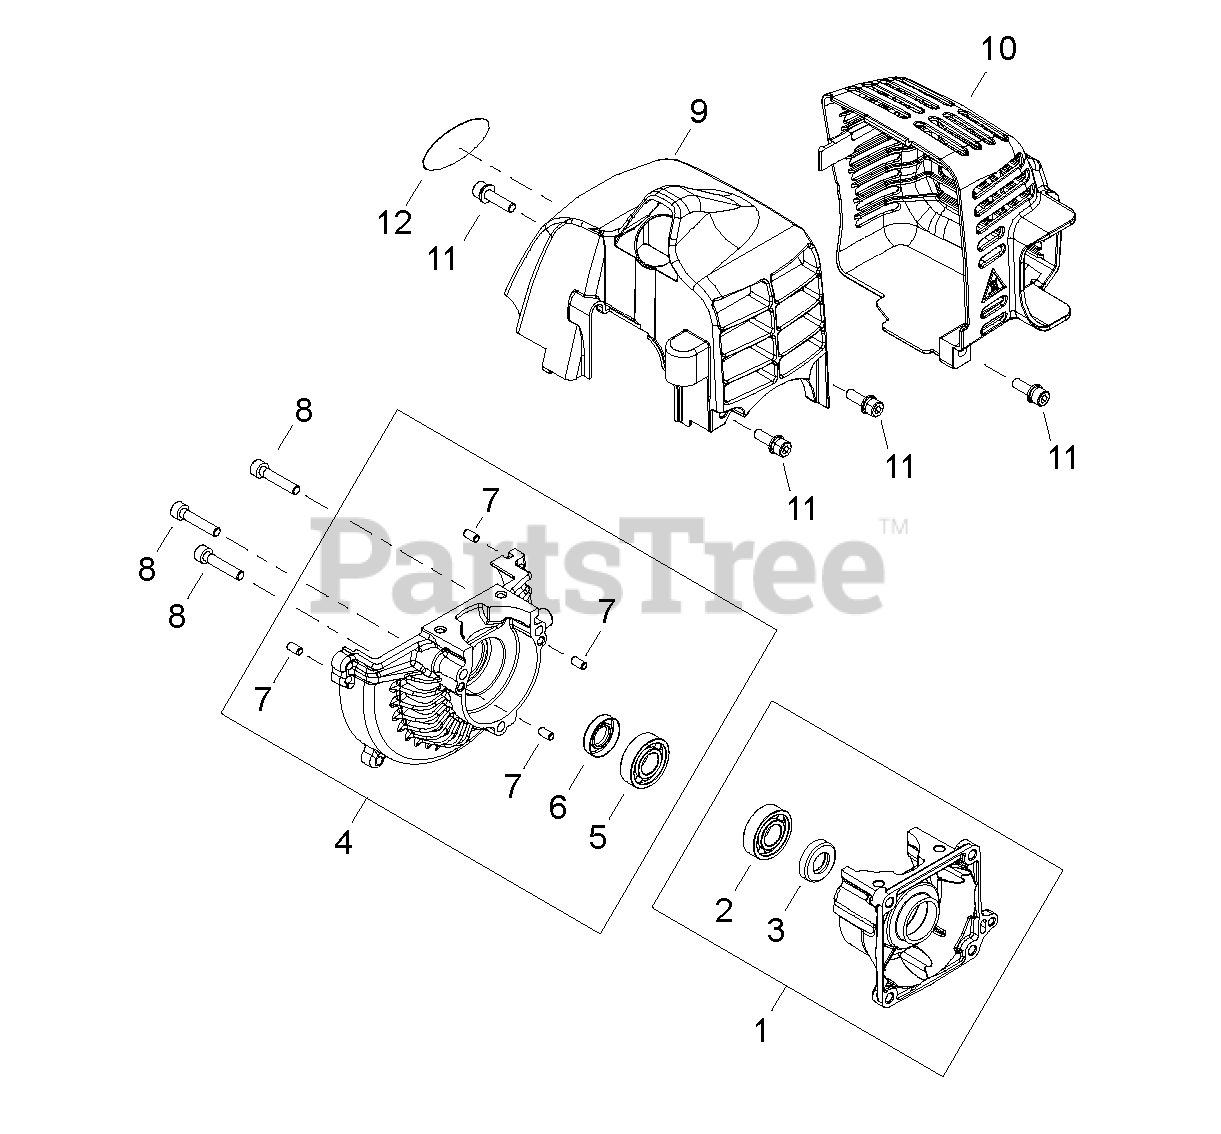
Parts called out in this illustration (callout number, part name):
1	CRANKCASE ASSY, S
2	BEARING, BALL 6201 C3
3	SEAL, OIL
4	CRANKCASE ASSY, M
5	BEARING, BALL 6201 C3
6	SEAL, OIL
7	PIN, LOCATING Ø4×8
8	BOLT 5×25
9	COVER, ENGINE
10	COVER, MUFFLER
11	BOLT, ADHESIVE M5×20
12	LABEL - MODEL 282
